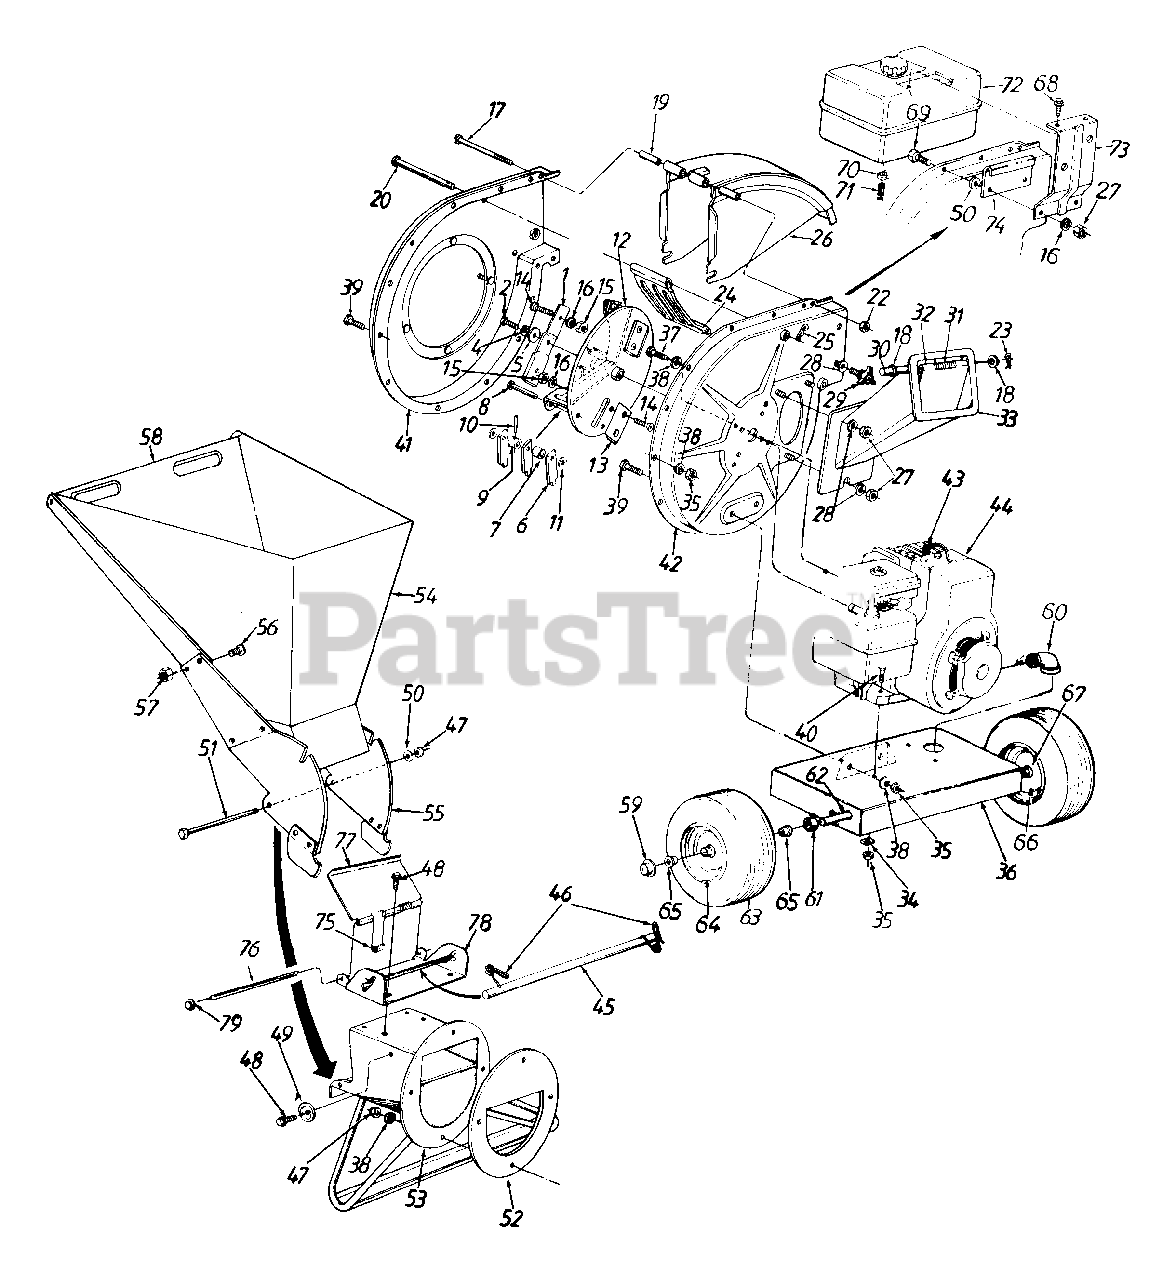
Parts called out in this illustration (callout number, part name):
1	Blade
2	Hex Patch Bolt 3/8-24 x 2.25" (Gr. 8)
4	L-Wash. 3/8" I.D. H.D.
5	Fl-Wash. .406" I.D. x 1.25" O.D. Hdn.
6	Flail
7	Flail Spacer
8	Clevis Pin .496" Dia.
9	Flail Spacer w/.160" Dia. Hole
10	Spring Roll Pin 1.12" Lg.
11	Fl-Wash. .531" I.D. x .94" O.D.
12	Impeller Ass'y. Comp
13	Chipper Blade
14	Flat Hd. Scr. 5/16-24 x .75" Lg.
15	Hex Top L-Nut 5/16-24 (Gr. 5)
16	L-Wash. 5/16" I.D.
17	Hex Bolt 1/4-20 x 3.75" Lg.
18	Fl-Wash. .281" I.D. x .5" O.D.
19	Chute Hinge Spacer 1.66" Lg.
20	Clevis Pin .5" Dia. x 4.62" Lg.
22	Hex Ctr. L-Nut 1/4-20 Thd.
25	Internal Cotter Pin 3/8" Dia.
27	Hex Nut 5/16-18 Thd. (Gr. 5)
28	Bell-Wash. .345" I.D. x .88"
30	Chipper Door Rod
31	Torsion Spring 1.14" Lg.
35	Hex Nut 5/16-18 Thd. (Gr. 5)
37	Hex Bolt 5/16-24 x .75" Lg.
38	L-Wash. 5/16" I.D.
39	Hex Bolt 5/16-18 x .75" Lg. (Gr. 5)
40	Hex Bolt 5/16-18 x 1.75" Lg.
44	Engine
46	Torsion Spring 1.06" Lg
47	Elastic Lock Nut 5/16-18 Thd
48	Hex Wash Hd Self-Tap Scr 5/16-18 x .75" Lg
49	Stop Washer
50	Fl-Wash 5/16" I.D.
51	Hex Bolt 5/16-18 x 8.38" Lg.
57	Hex L-Nut 1/4-20 Thd
60	Drain Elbow (645C)
61	Spacer 64" I.D. x .38" Lg.
62	Shredder Axle
66	Air Valve
67	Grease Fitting
68	Hex Hi-Low Scr 1/4" x .75" Lg.
69	Hex Bolt 5/16-18 x .88" Lg.
70	Hose Clamp
71	Fuel Line - 7" Lg
72	Fuel Tank Ass'y Comp
76	Hopper Door Rod
